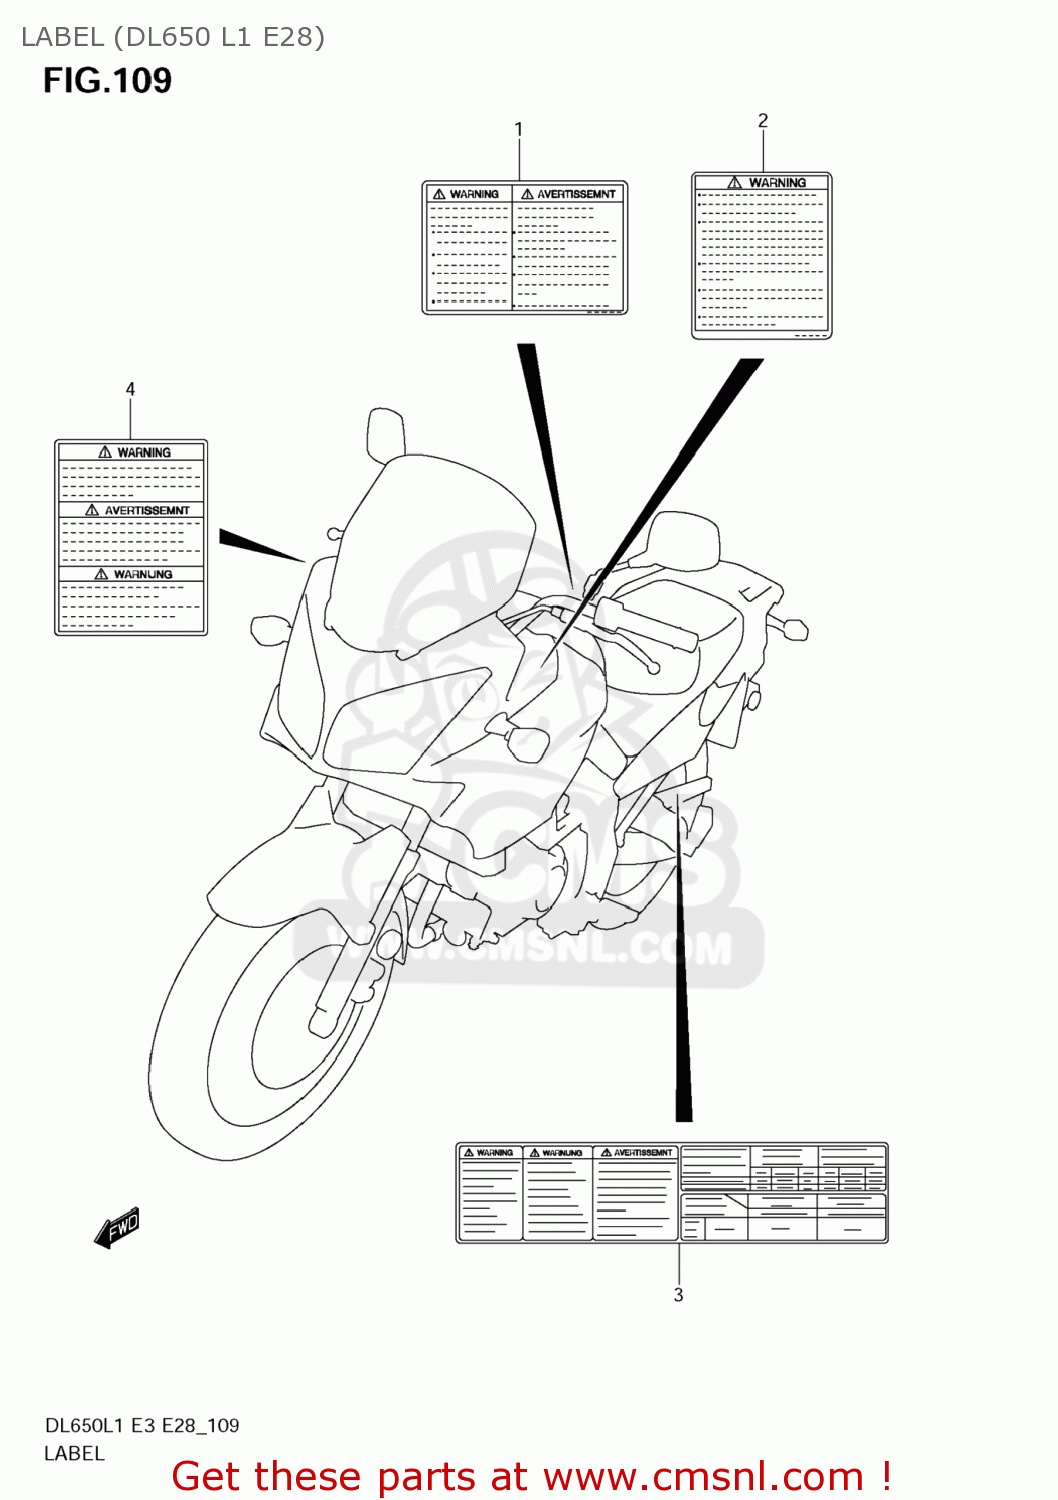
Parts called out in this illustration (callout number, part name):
1	LABEL,GENERAL WARNING
2	LABEL,SCREEN
3	LABEL,TIRE INFORMATION
4	LABEL,WARNING STEERING
5	MANUAL,OWNER'S
